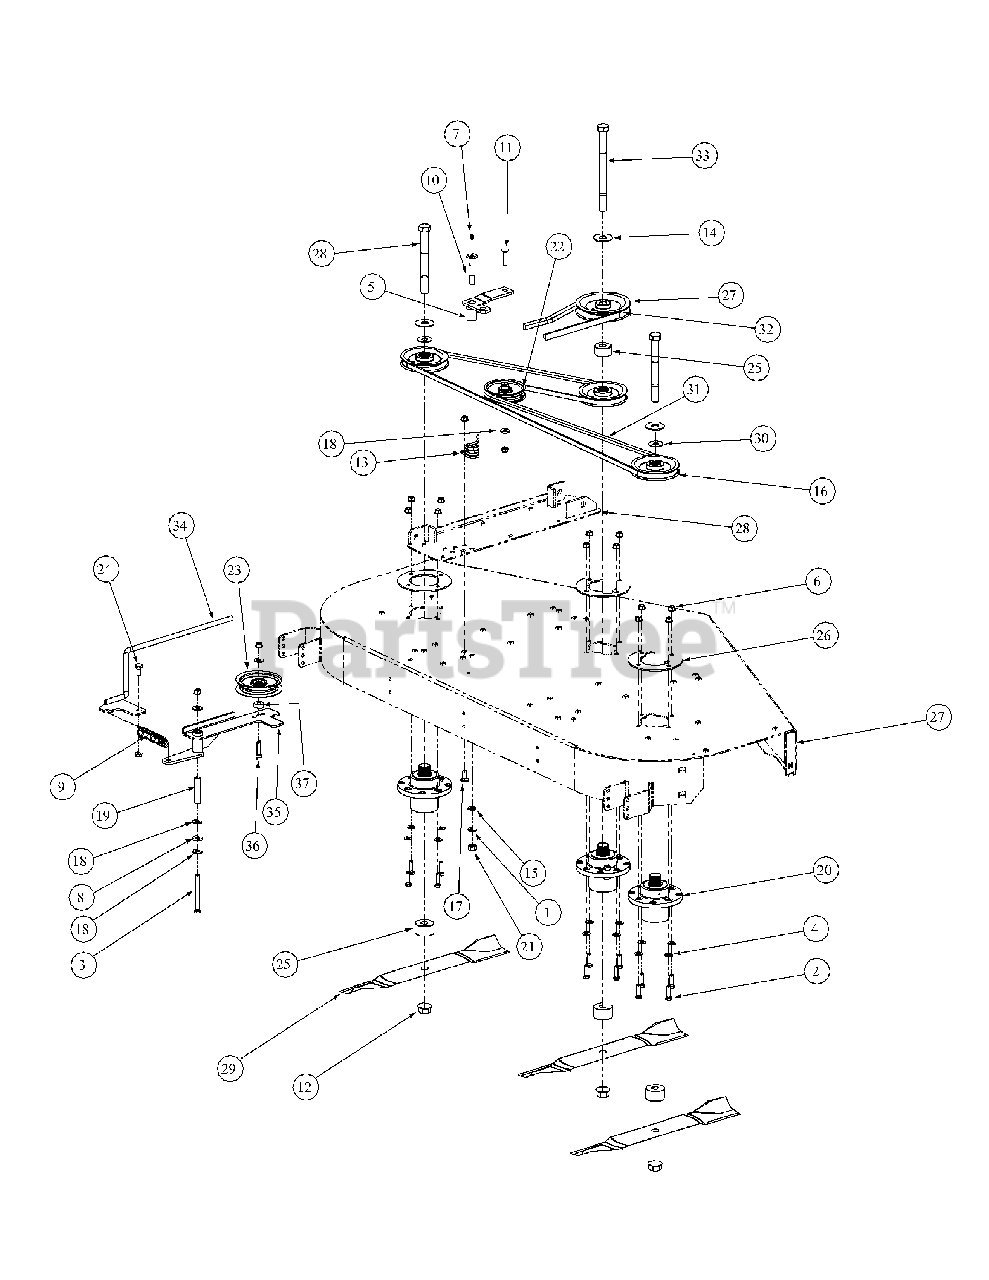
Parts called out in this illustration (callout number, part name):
1	Lock Washer, 7/16
2	Hex Cap Screw, 3/8-16 x 1-1/2
3	Hex Cap Screw, 3/8-16, 4.00
4	Flat Washer, 3/8 12
5	Idler Arm Casting, Deck Spindle
6	Flange Lock Hex Nut, 3/8-16
7	Grease Fitting, 1/4-28 x 3/16
8	Idler Washer
9	Extension Spring, .98 x OD x 5.000
10	Shoulder Screw, 7/16-14
11	Hex Carriage Screw, 3/8-16, 1.75
12	Flange Hex Nut, 3/4-16
13	Torsion Idler Spring
14	Flat Washer, .781 ID 2.00 OD, .105
15	Flat Washer, .469 ID, .875 OD, .105
16	V-Pulley, 5.00 OD
17	Carriage Bolt, 3/8-16 x 1
18	Flat Washer, .406 ID, 1.0 OD, .105
19	Spacer, .39 ID x .625 OD x 2.75
20	Aluminum Spindle Assembly
21	Hex Nut, 7/16-14
22	Flat Pulley
23	Idler Pulley, 4.06 OD
24	Shoulder Screw, .50 x .27 Lg., 3/8-16
25	Spacer, .760 ID x 2.00 OD x .925
26	Aluminum Spindle Support Plate
27	V-Pulley, Cast, 6.360 OD
28	Hex Cap Screw, 3/4-16, 7.00
29	Hi-Lift Blade, 21.0, 0.756 ID
30	Spacer .812 ID x .218 LG
31	V-Belt, A Section x 122.3
32	V-Belt, B Section x 147.4
33	Hex Cap Screw, 3/4-16, 9.00
34	Spring Tension Rod Assembly
35	Idler Arm Assembly, Flat Top Bearing
35	Bearing Sleeve
36	Hex Cap Screw, 3/8-16 x 2.00
37	Spacer, .406 ID x 1.00 OD x .38
